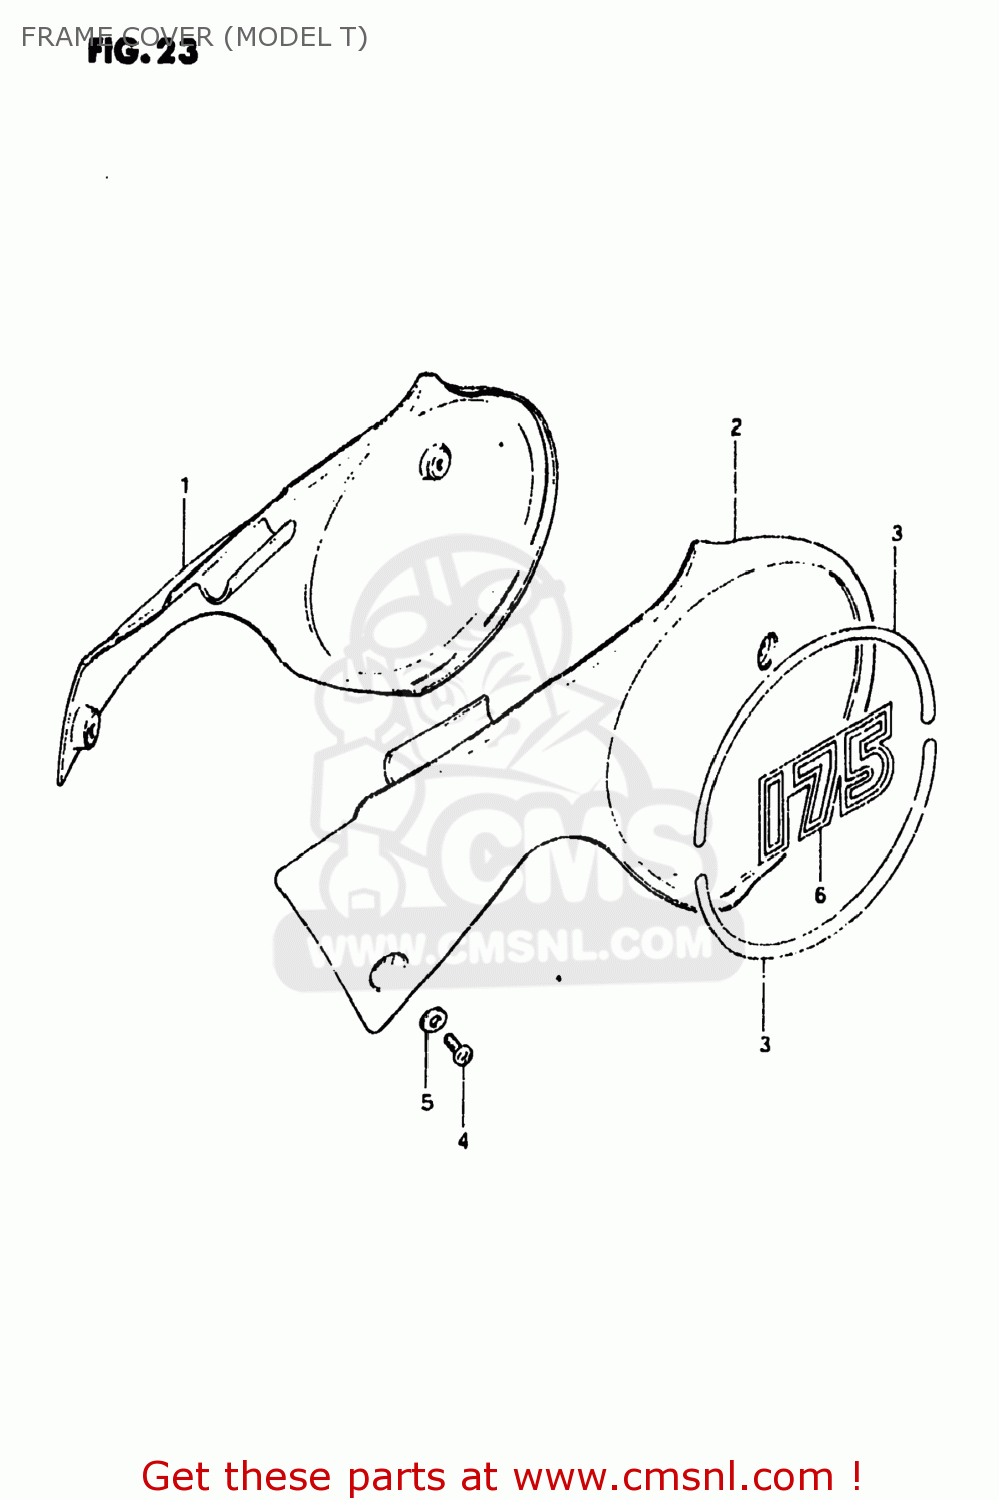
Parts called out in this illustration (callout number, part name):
1	COVER,FRAME,R(YELLOW)
2	COVER,FRAME,L(YELLOW)
3	TAPE,FRAME COVER
4	SCREW 6X12
5	WASHER
6	EMBLEM
